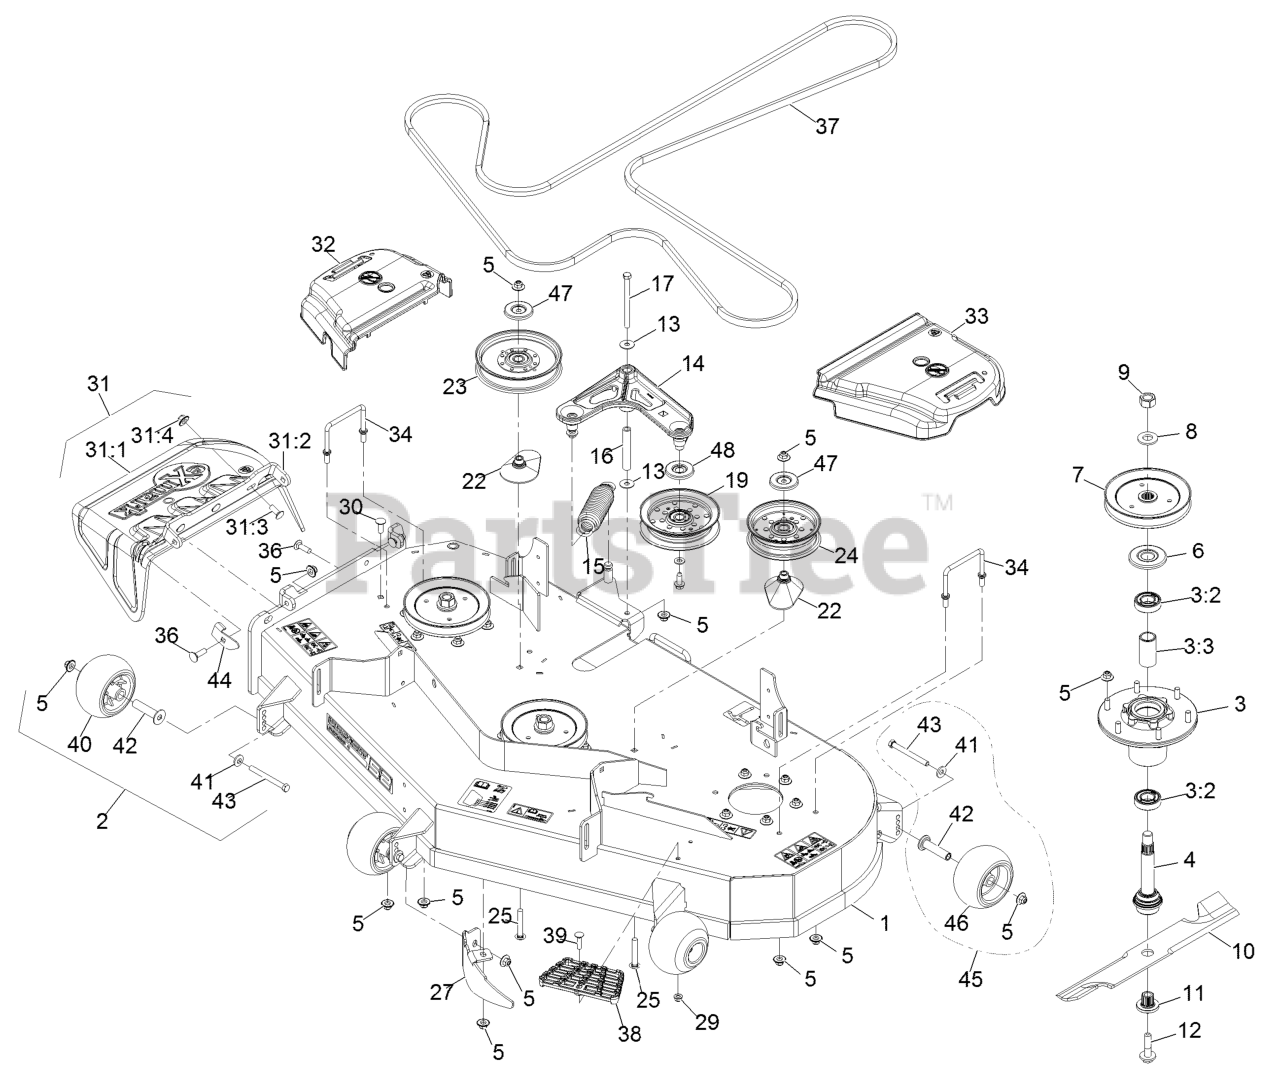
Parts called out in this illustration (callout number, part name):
1	ASM-Deck W/Decals 524
2	Kit, Anti-Scalp Roller
3	ASM-Cutter Hsg With Bearings
3:2	Bearing-Ball
3:3	Spacer-Bearing
4	ASM-Spindle And Seal
5	Nut-Nyloc 3/8-16 Flg
6	Guard,Bearing Top .989
7	Sheave,Blade Drive 6.50
8	Washer-Spring Disc 3/4
9	Nut-Hex
10	Blade-Extreme 2, 18.00"
10	Blade-Notched
10	Blade, Mulching
10	Blade, Low Lift
10	Blade, Solid
11	Bushing, Splined
12	Screw-Sems 1/2-20 X 2.19
14	Idler Arm ASM
15	Spring-Extension
16	Bushing
17	Screw-HH 3/8-16 X 4 3/4
19	Idler-Pulley, Flat
22	Spacer-Pulley
23	Idler-Pulley, Flat 6.00X1.00
24	Idler-Pulley, Flat 5.00X1.31
25	Bolt-Carriage 3/8-16 X 2 1/2
27	Baffle-Dogleg, Lz-Vt52
29	Nut-Nyloc 5/16-18 Flg
30	Bolt-Carriage 3/8-16 X 1
31	ASM,Discharge Chute
31:1	Chute, Discharge
31:2	Bracket,Discharge Chute
31:3	Bolt-Carriage 3/8-16 X 1
31:4	Nut-Nyloc 3/8-16 Flg
32	Cover-Belt, RH
33	Cover-Belt, LH
34	Wireform-Cover
36	Bolt-Carriage 3/8-16 X 1 1/4
37	Belt-V
38	Step-Deck
39	Bolt-Carriage 5/16-18 X 1 1/4
40	Roller-Anti-Scalp
41	Washer-Spring Disc 3/8
42	Axle, Roller
43	Screw-HH 3/8-16 X 3 3/4 GR 8
44	Stop-Discharge Chute
45	Kit-Antiscalp Roller
46	Roller-Scalp, Anti
47	Shield-Dust
48	Shield-Guard, Dust
